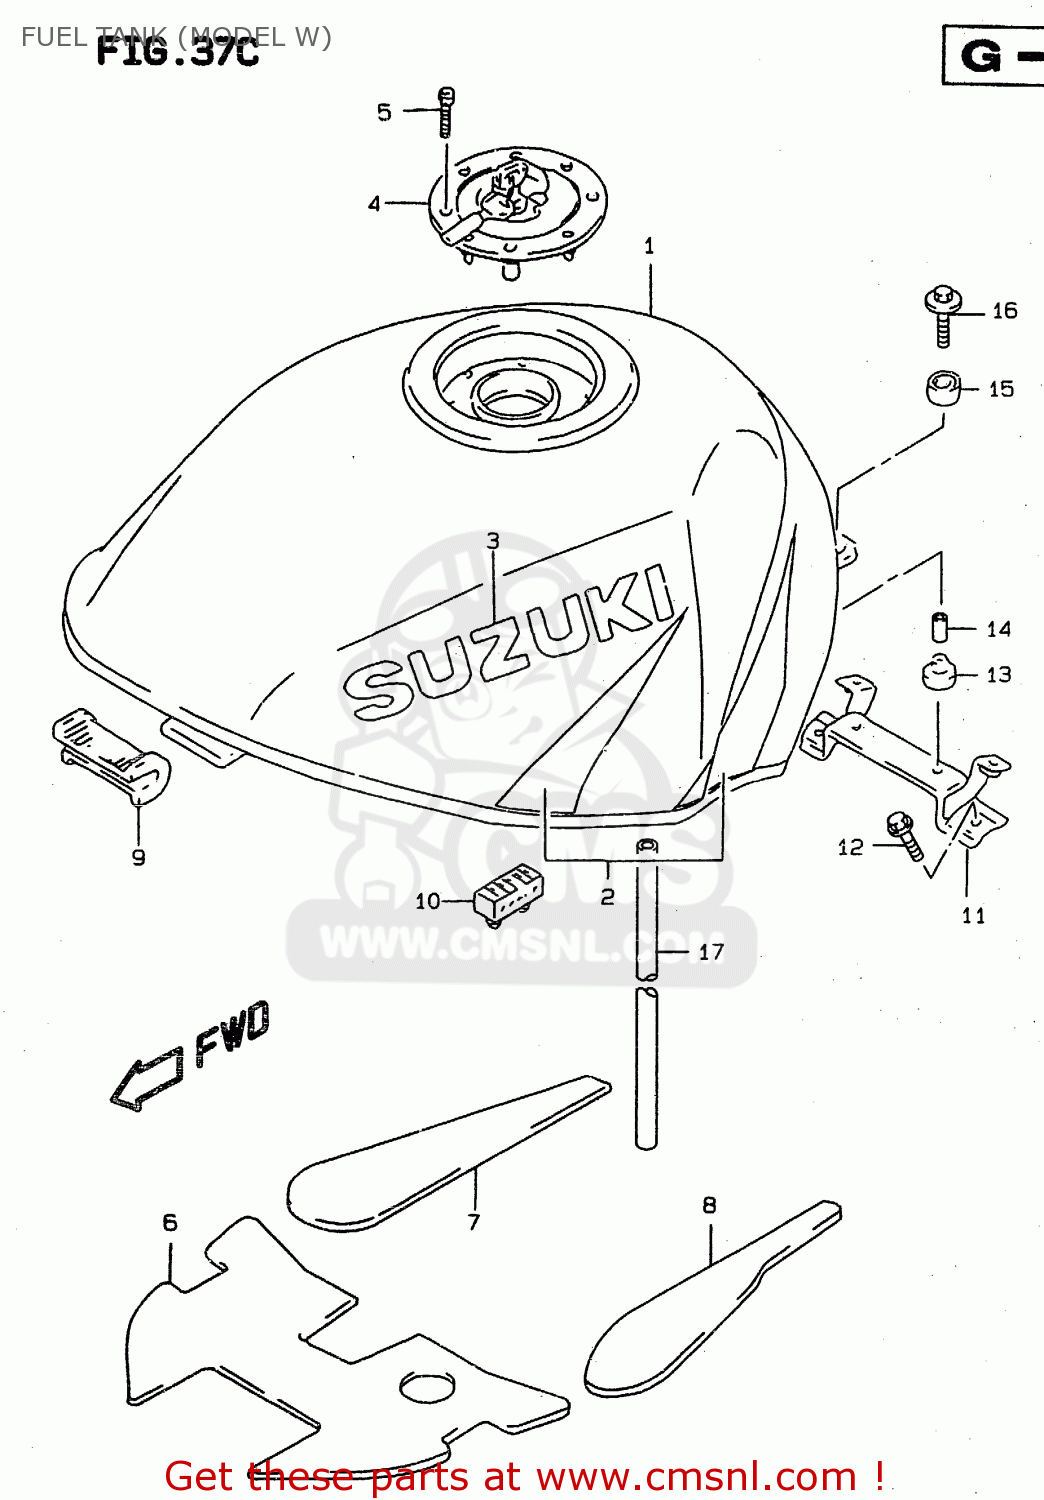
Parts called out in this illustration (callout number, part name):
1	TANK ASSY,FUEL(MAROON)
2	TAPE SET,FUEL TANK
3	EMBLEM (SILVER)
4	CAP SET,FUEL TANK
5	BOLT(5X20)
6	SHIELD,FUEL TANK HEAT NO.1
7	SHIELD,FUEL TANK HEAT NO.2
8	SHIELD,FUEL TANK HEAT NO.3
9	CUSHION,FUEL TANK FR
10	CUSHION,SEAT(40X20X15)
11	BRACKET,FUEL TANK RR
12	BOLT
13	CUSHION
14	SPACER(6.5X9X18)
15	CUSHION
16	BOLT
17	HOSE(7X10.2X600)
